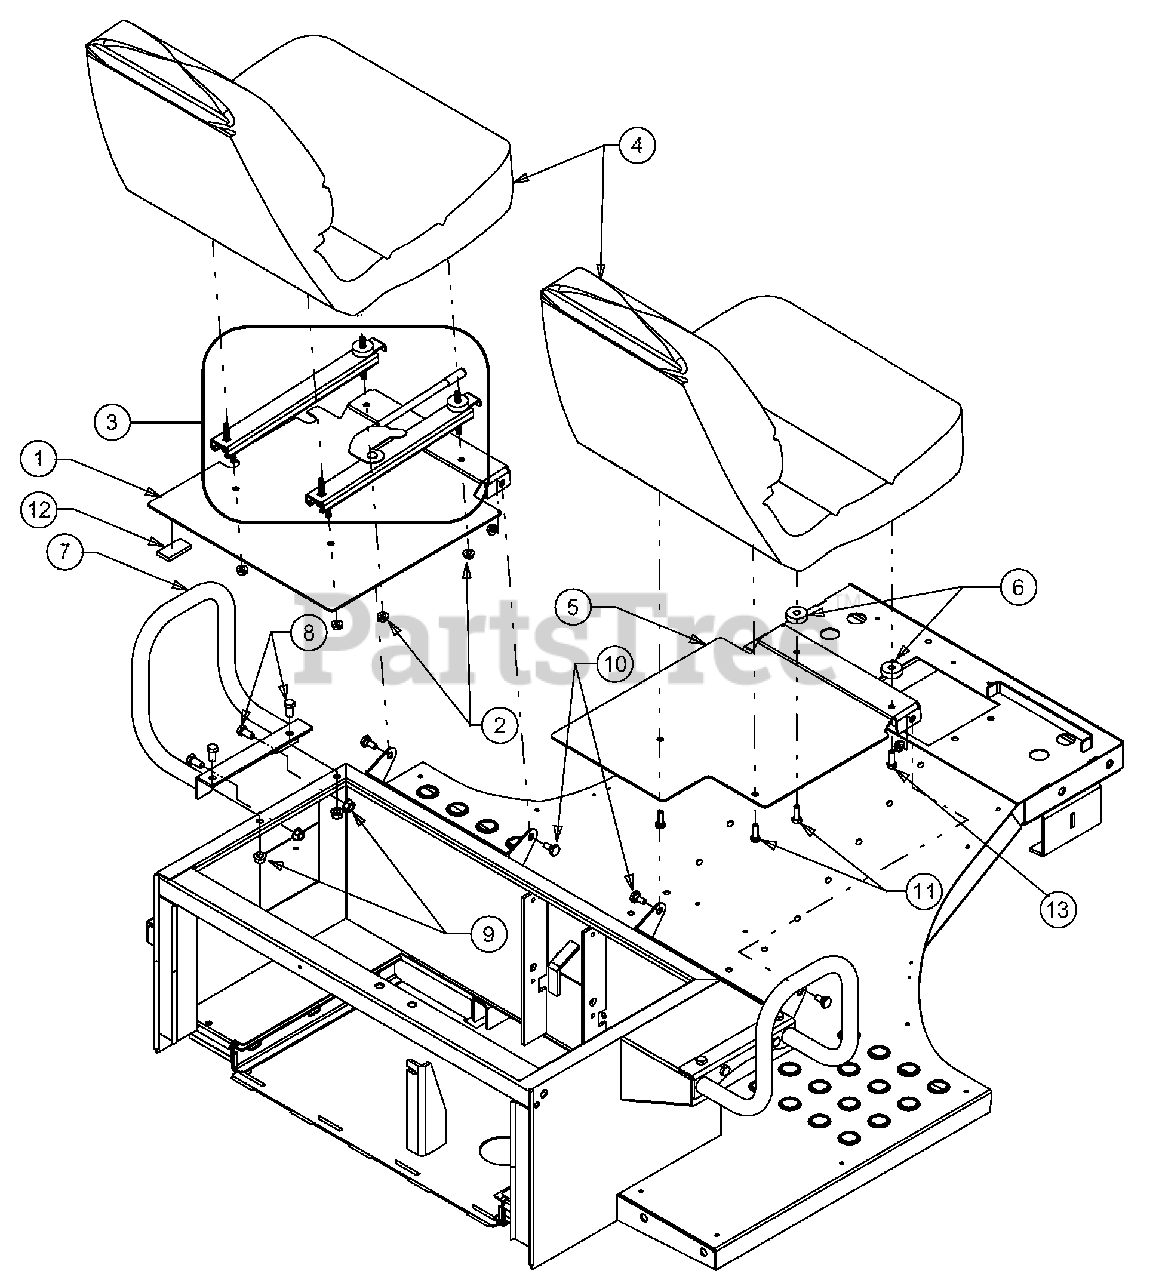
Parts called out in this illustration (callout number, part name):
1	Plate, Seat, LH
2	Nut, Flange Lock, 5/16-18, Gr5
3	Track Assembly, Seat
4	Seat
5	Plate, Seat, RH
6	Spacer, Seat
9	Nut, Flange Lock, 3/8-16
10	Shoulder Screw, .435 x .178-5/16 x .56
11	Hex Screw, 5/16-18 x .625, Gr5
12	Bumper .62 Dia x .3
13	Hex Screw 5/16-18 x 1.00 Gr 5
